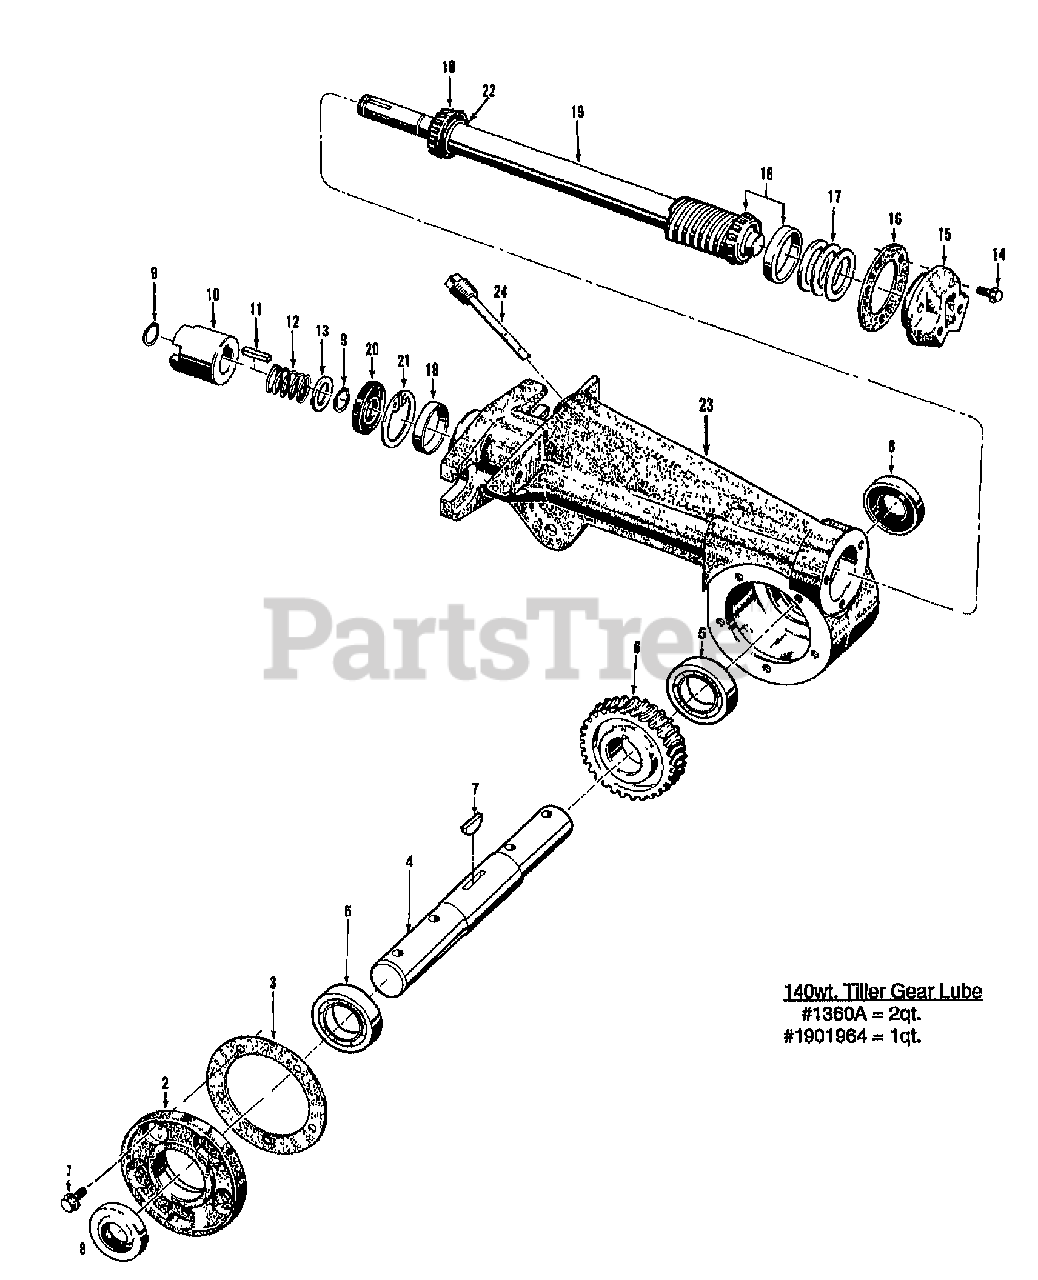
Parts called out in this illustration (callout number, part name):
1	KIT-SEALING SCRS (5)W/LIT
2	COVER-TILLER HSG MACH
3	GASKET-TILLER COVER
4	SHAFT-TILLER MACH HORSE
5	BEARING-BALL
6	GEAR-WORM MACH RTH HORSE
7	KEY-WOODRUFF .25X1.12
8	SEAL-TILLER SHAFT
9	RING-RETAIN EXT .707 ID
10	KIT-CLUTCH DOGS TILLER
10	CLUTCH-DOG HORSE TRANS
11	KEY-.188 SQX1.0
12	SPRING (TC)
13	SHIM-1.0X.7656X.062
14	KIT-SEALING SCRS (3)
15	CAP-REAR #1115
16	GASKET-BRG COVER
17	SHIM-1.75X1.5X.01
17	SHIM-1.75X1.5X.03
17	SHIM-1.75X1.5X.005
17	SHIM-1.75X1.5X.062
18	KIT-BRG CONE&RACE-DRIVESHAFT
19	KIT-TILLER DR SHAFT
20	SEAL-OIL DRIVESHAFT
21	RING-RETAINING 5000-181
22	SHIM-1.0X.7656X.062
23	HOUSING-TILLER W/SLEEVE
24	ASSM-DIPSTICK HORSE TRANS
